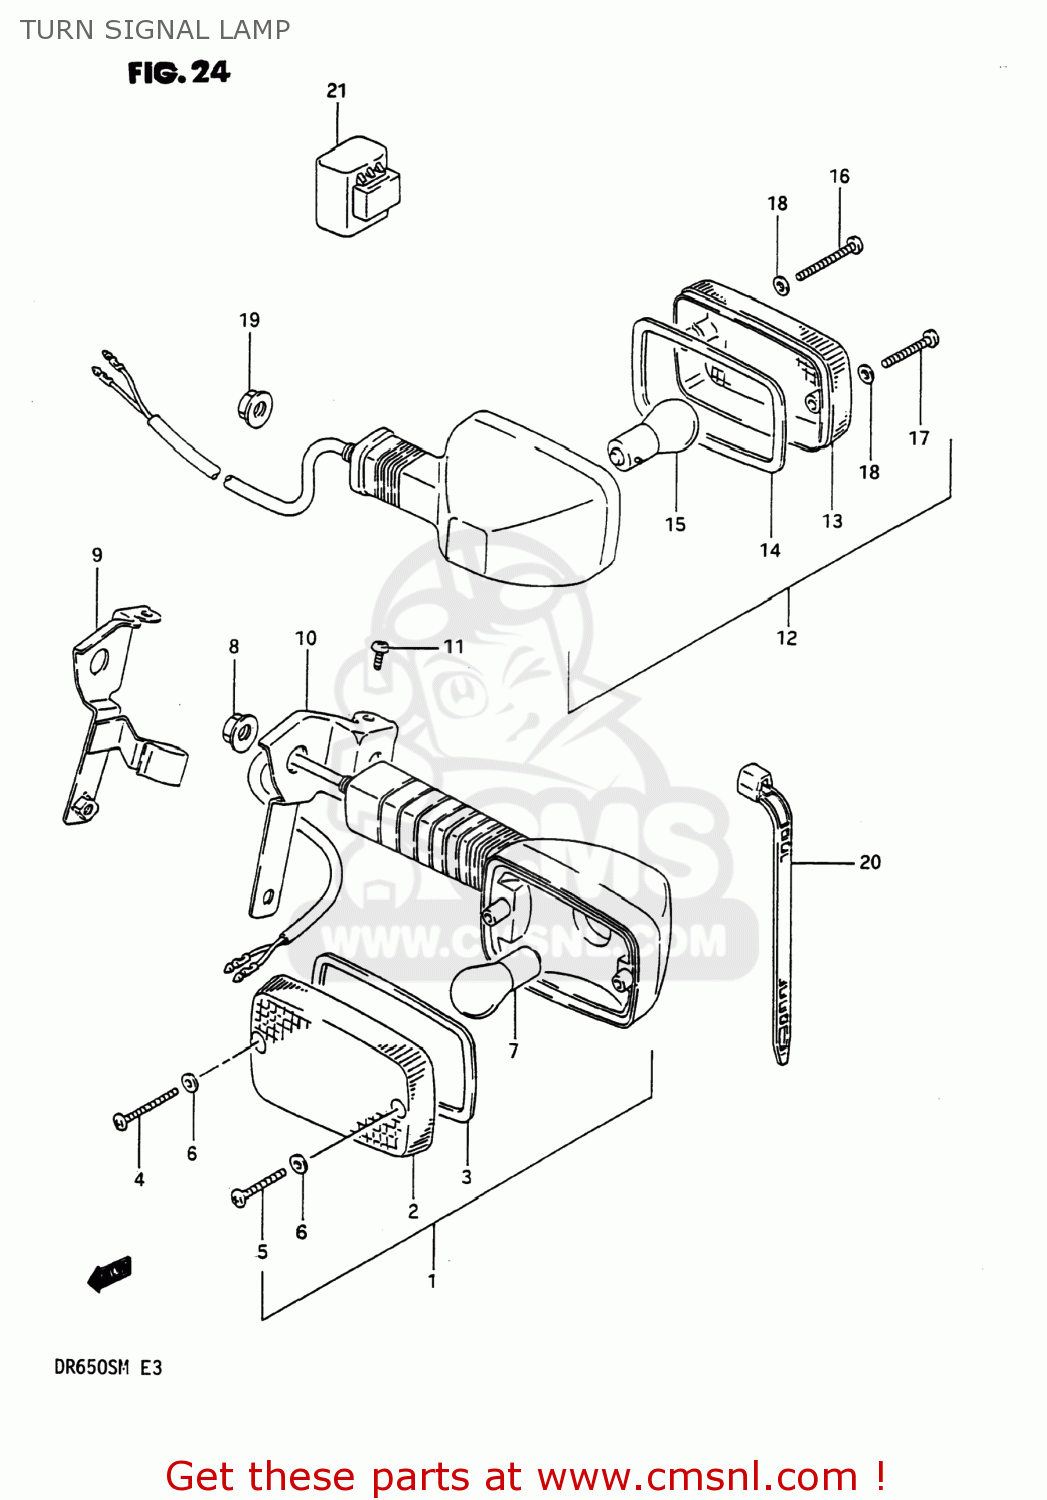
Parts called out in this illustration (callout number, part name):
1	LAMP ASSEMBLY,FRONT TURN SIGNAL
2	LENS,FR
3	GASKET (NAS)
4	SCREW,TURN SIG LENS FITTING
5	SCREW
6	GASKET (NAS)
7	BULB(12V23W,STANLEY,A4577A)
8	NUT
9	BRACKET,FRONT TURN SIGNAL
10	BRACKET,FRONT TURN SIGNAL
11	SCREW
12	LAMP ASSEMBLY,REAR TURN SIGNAL
13	LENS,RR
14	GASKET (NAS)
15	BULB(12V23W,STANLEY,A4577A)
16	SCREW,TURN SIG LENS FITTING
17	SCREW
18	GASKET (NAS)
19	NUT
20	CLAMP(L:125)
21	RELAY ASSEMBLY,TURN SIGNAL
